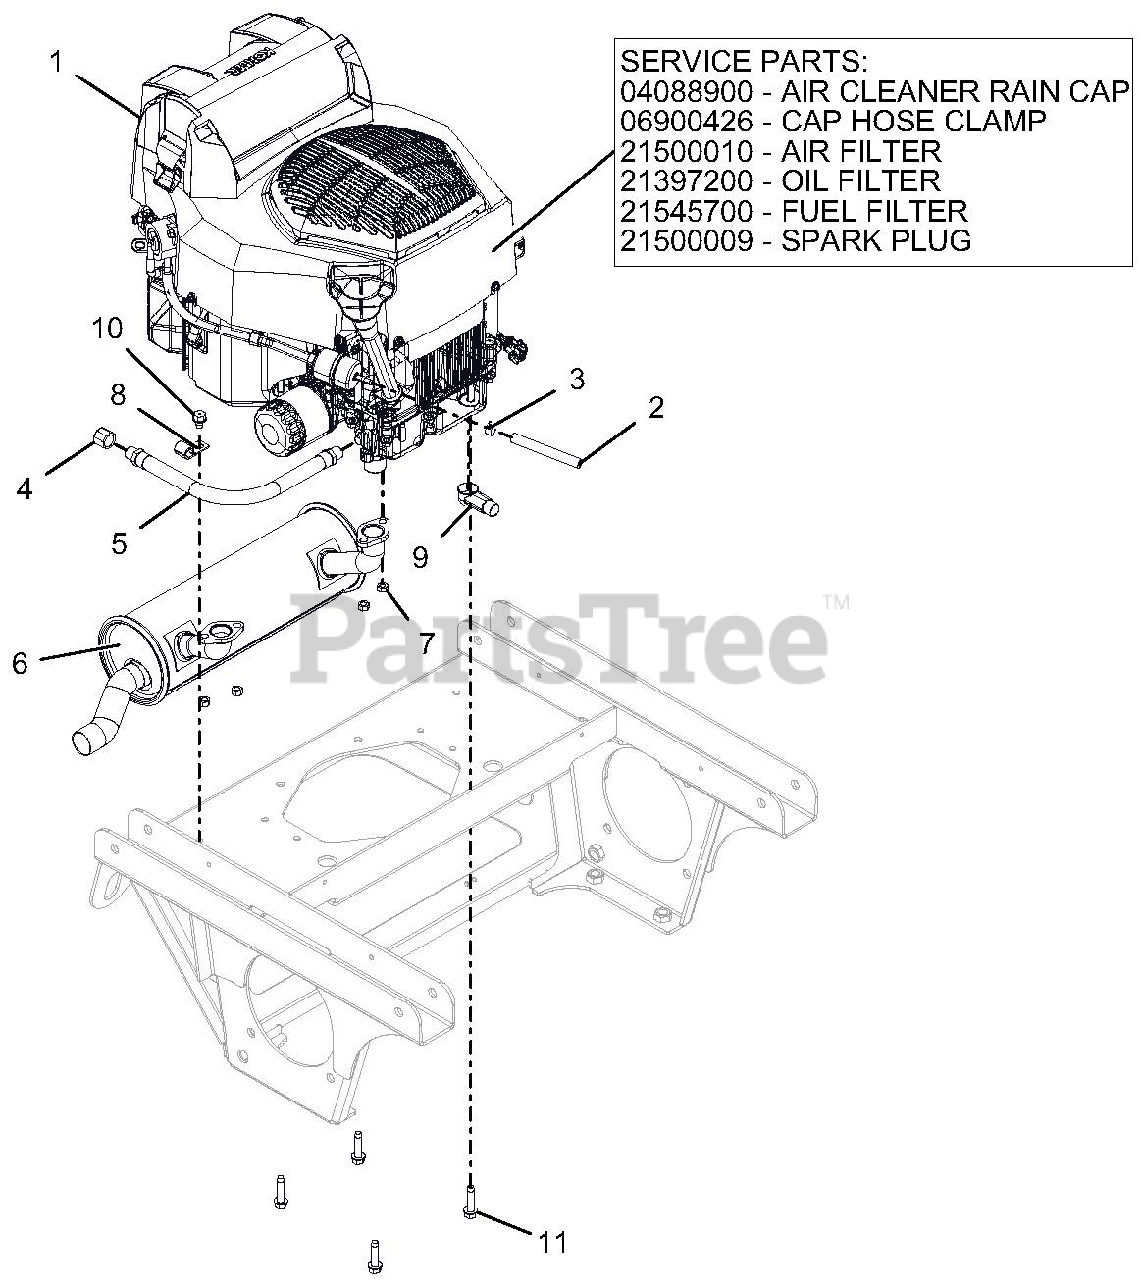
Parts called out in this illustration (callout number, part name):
1	AIR CLEANER RAIN CAP
1	CAP HOSE CLAMP
1	AIR FILTER
1	OIL FILTER
1	FUEL FILTER
1	SPARK PLUG
1	ENGINE, KOHLER ZT740 CONFIDANT
2	.25 LOW-PERM GAS HOSE 42.00" LG - VALVE TO ENGINE
3	CLAMP, FUEL LINE
4	PIPE, CAP 3/8 NPT FEMALE
5	HOSE, HYD .38-11-OK M6N0-M6N0
6	MUFFLER, ZT730, ZT740
7	NUT-LK-TOP M8-1.25 YWZC
9	BOOT, .65 ID POS
10	SCR-TAP .38-16X.50 HWH TR YWZ
11	SCR-TAP .38-16X1.50 HWH TR YZ
